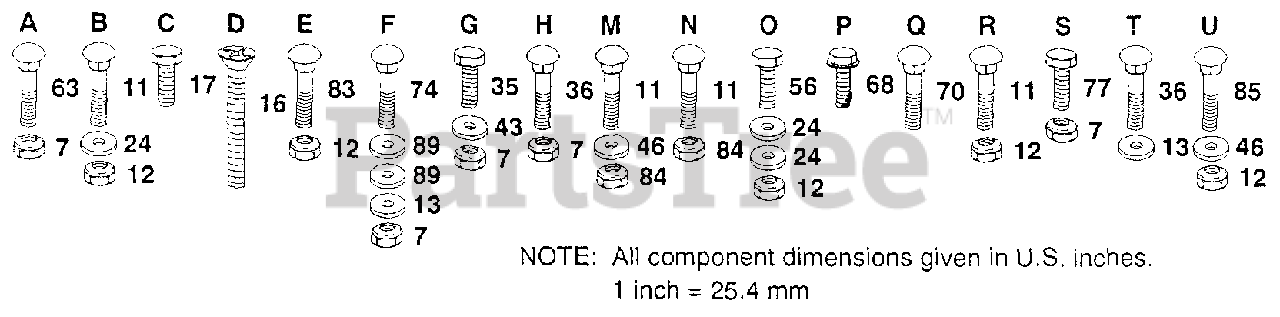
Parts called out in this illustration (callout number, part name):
11	BOLT
13	WASHER
16	SCREW YT
24	WASHER M
35	BOLT - HEX 3/8 - 16 X 3
43	WASHER
46	WASHER
56	BOLT
63	BOLT
68	SCREW
70	BOLT
74	BOLT
77	BOLT
83	BOLT
89	WASHER
